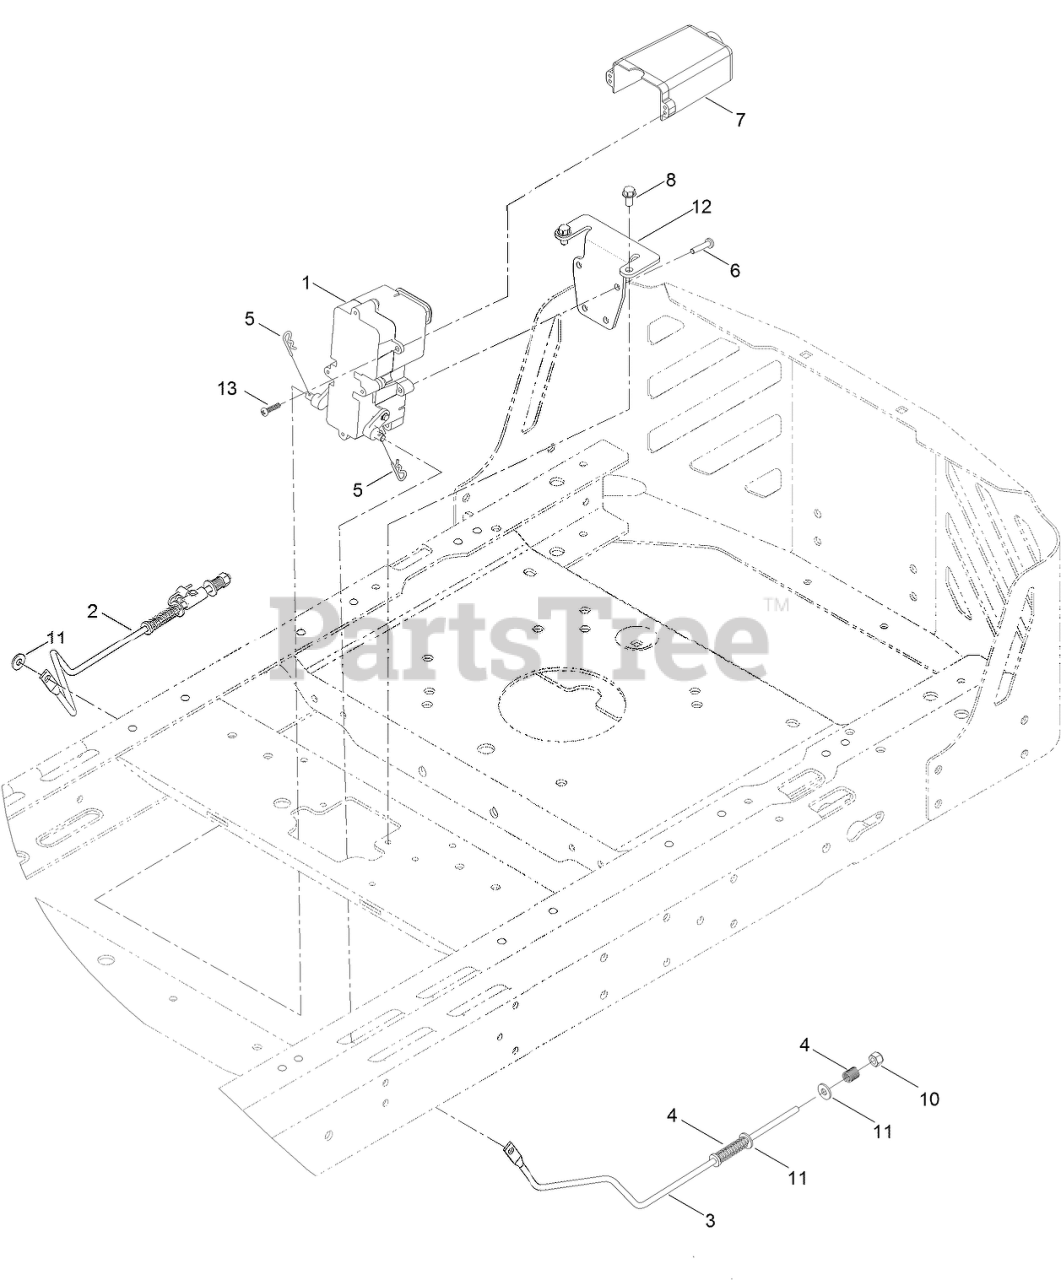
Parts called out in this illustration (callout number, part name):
1	BRAKE BOX ASM
2	ROD-BRAKE, WIDE (RH)
3	ROD-BRAKE, WIDE (LH)
4	SPRING-COMPRESSION
5	PIN-COTTER
6	SCREW-PPH
7	COVER-CONNECTOR
8	SCREW-HWH
10	NUT-LOCK, NI
11	WASHER
12	BRACKET-MOUNT, BRAKE
13	SCREW-PPH
